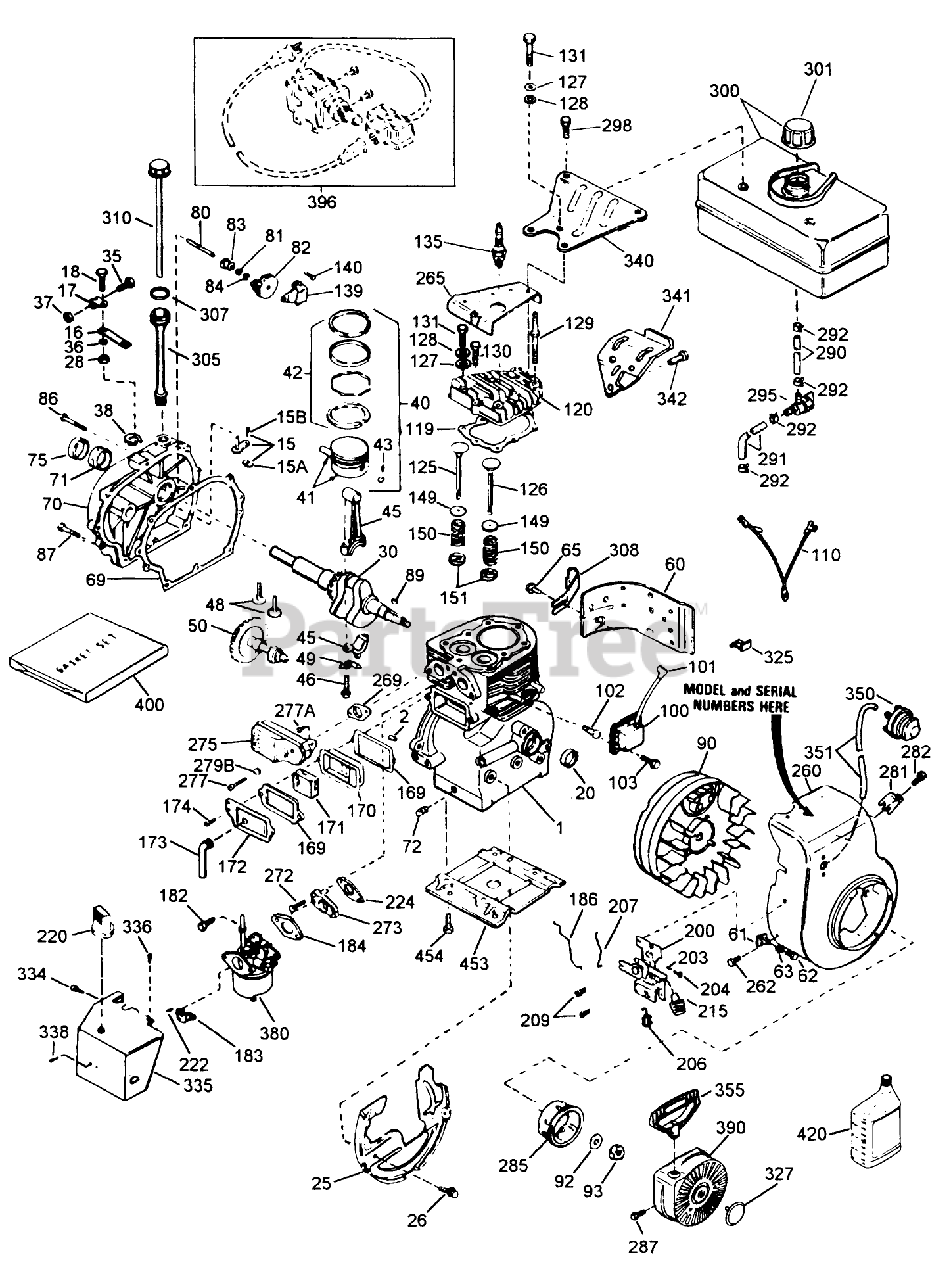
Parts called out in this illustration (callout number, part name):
1	Cylinder Assy. (Incl. Ref. #2, 3 4)
2	Pin-Dowel
15	Rod, Governor (Incl. Nos.62 63)
15A	Yoke-Governor
15B	Screw (6-40x5/16)
16	Lever-Governor
17	Clamp-Lever, Governor
18	Screw
20	Oil Seal
25	Baffle-Blower Housing
26	Screw (1/4-20x19/32)
28	Nut-Lock
30	Crankshaft
35	Screw
36	Washer-Lock
37	Nut-Lock
38	Ring-Retaining
40	Piston, Pin Ring Assy. (.010 oversize) (Incl. Ref. #19A, 20 21 )
40	Piston, Pin Ring Assy. (.020 oversize) (Incl. Ref. #19A, 20 21)
40	Piston, Pin Ring Assy. (Std.) (Incl. Ref. #19A, 20 21)
41	Piston Pin Assy. (.010 oversize) (Incl. Ref. #20)
41	Piston Pin Assy-. (.020 oversize) (Incl. Ref. #20)
41	Piston Pin Assy. (Std.) (Incl. Ref. #20)
42	ORing
42	Ring Set (.020" OS)
42	Ring Set (.010" OS)
45	Rod Assy., Connecting (Incl. Nos. 10 18)
46	Bolt-Connecting Rod
48	Lifter-Valve
49	Dipper-Oil
50	Camshaft
60	Extension-Blower Hsng.
61	Bracket
62	Screw (8-32 x 3/8)
63	Grommet
65	Screw
69	Gasket-Cover, Cylinder
70	Cylinder Cover (Incl. Ref. #71, 75, 80)
71	Bushing-Crankshaft
72	Plug-Drain, Oil (SQH 1/4-18)
75	Oil Seal
80	Shaft-Governor
81	Washer-Flat
82	Governor Gear ASM
83	Spool-Governor
84	Ring-Retaining
86	Screw (1/4-20 x 1-1/4)
87	Screw
89	Key-Flywheel
90	Flywheel
92	Washer-Belleville
93	Flywheel Nut
100	Solid State
101	Cover-Spark Plug
103	Screw
110	Ground Wire
119	Cylinder Head Gasket
120	Cylinder Head (Incl. 3 of 131)
125	Valve, Exhaust (Standard)(Incl. No. 9)
125	Valve, Exhaust (1/32" oversize)(Incl. No. 9)
126	Valve, Intake (1/32" oversize)(Incl. No. 9)
126	Valve, Intake (Standard)(Incl. No. 9)
127	Washer-Flat
128	Washer-Belleville
129	Screw (5/16-18 X 2-1/2)
130	Screw (5/16-18 X 2-1/2)
131	Screw (5/16-18 X 2-1/2)
135	Spark Plug-Resistor (R J19 L M)
139	Bracket, Governor
140	Screw, Torx T-25
149	Cap-Spring, Valve
150	Spring-Valve
151	Keeper-Spring, Valve
169	Gasket-Cover, Valve
170	Body-Breather
171	Element-Breather
172	Cover-Valve
173	Tube-Breather
174	Screw
182	Screw (T-30, 1/4-20 X 27-32)
183	Bracket-Choke
184	Gasket-Carburetor
186	Governor Link
200	Bracket-Control (Includes 19, 203, 204, 206)
203	Spring-Compression
204	Screw
206	Terminal
207	Link-Throttle
209	Screw (10-32 x 1/2)
215	Knob-Control
220	Knob-Choke
222	Screw (10-32 x 1/2)
224	Gasket-Pipe, Intake
260	Blower Housing
262	Screw
265	Cover-Head, Cylinder
269	Gasket-Exhaust
272	Screw
273	481-1279 SENATOR RO
275	Muffler
277	Screw (5/16-18 X 2)
277A	Screw
279B	Washer
281	Screw
282	Screw (8-32 x 3/8)
285	Cup-Starter
287	Screw (8-32 x 21/64)
290	Line-Fuel (8.62)
291	Line-Fuel
292	Clamp-Line, Fuel
295	Valve-Shut Off, Fuel
298	Screw (1/4-15x7/8)
299	Nut-U Type
300	Fuel Tank (Incl. Ref. #292 301)
301	Cap-Fuel
305	Tube-Fill, Oil
307	O-Ring
308	Clip-Tube, Fill
310	Dipstick
325	Clip-Wire
327	Plug Starter
334	Screw (8-32 X 5/16)
335	Carburetor Cover
336	Screw (10-32x1/2)
338	Screw (8-32 x 3/8)
340	Bracket-Fuel Tank
341	Bracket-Fuel Tank
342	Screw (1/4-20x19/32)
350	Primer-Asm
351	Line-Primer
355	Handle-Starter, Mitten Grip
380	Carburetor (Incl. Ref. #184)
390	Rewind Starter
396	Starter-Electric (110 Volt)
400	Gasket Set
420	4 Cycle Oil, SAE 30 (Quart)
453	Engine Mounting Base
454	Screw
